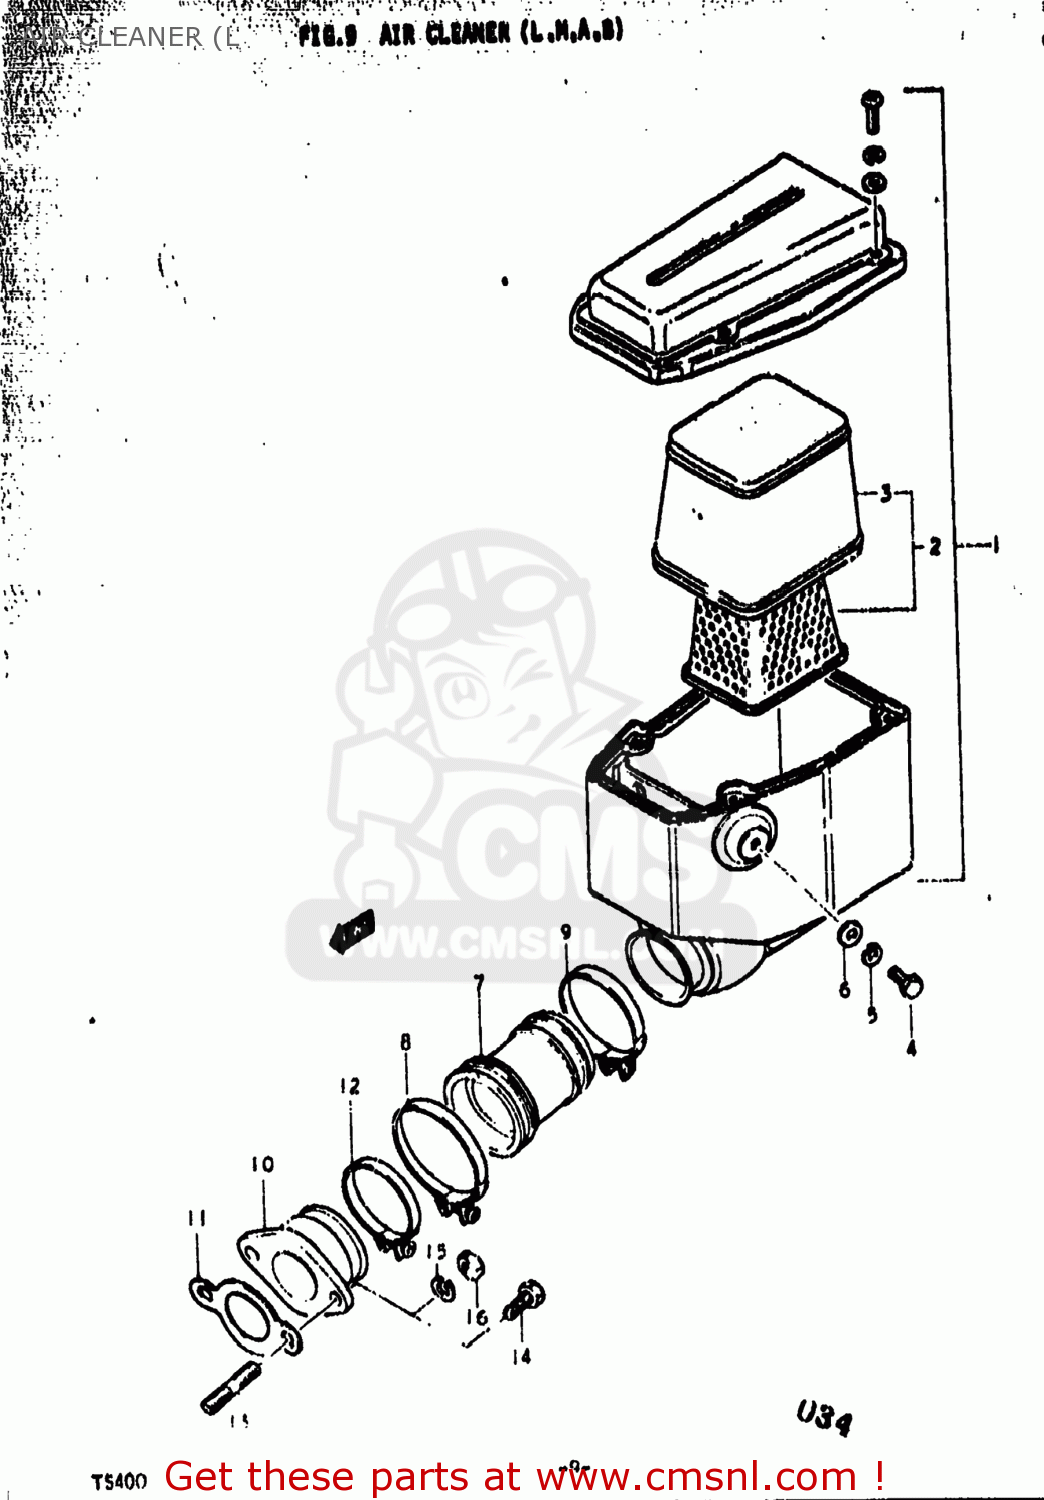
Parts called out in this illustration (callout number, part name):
1	CLEANER ASSEMBLY,AIR
2	FILTER,AIR CLEANER
3	FILTER
4	BOLT
5	LOCK WASHER
6	WASHER
7	TUBE,AIR CLEANER OUTLET
8	CLAMP
9	CLAMP
10	PIPE,INTAKE
11	GASKET,CARBURETOR (NAS)
12	CLAMP
13	STUD BOLT
14	BOLT
15	LOCK WASHER
16	NUT
